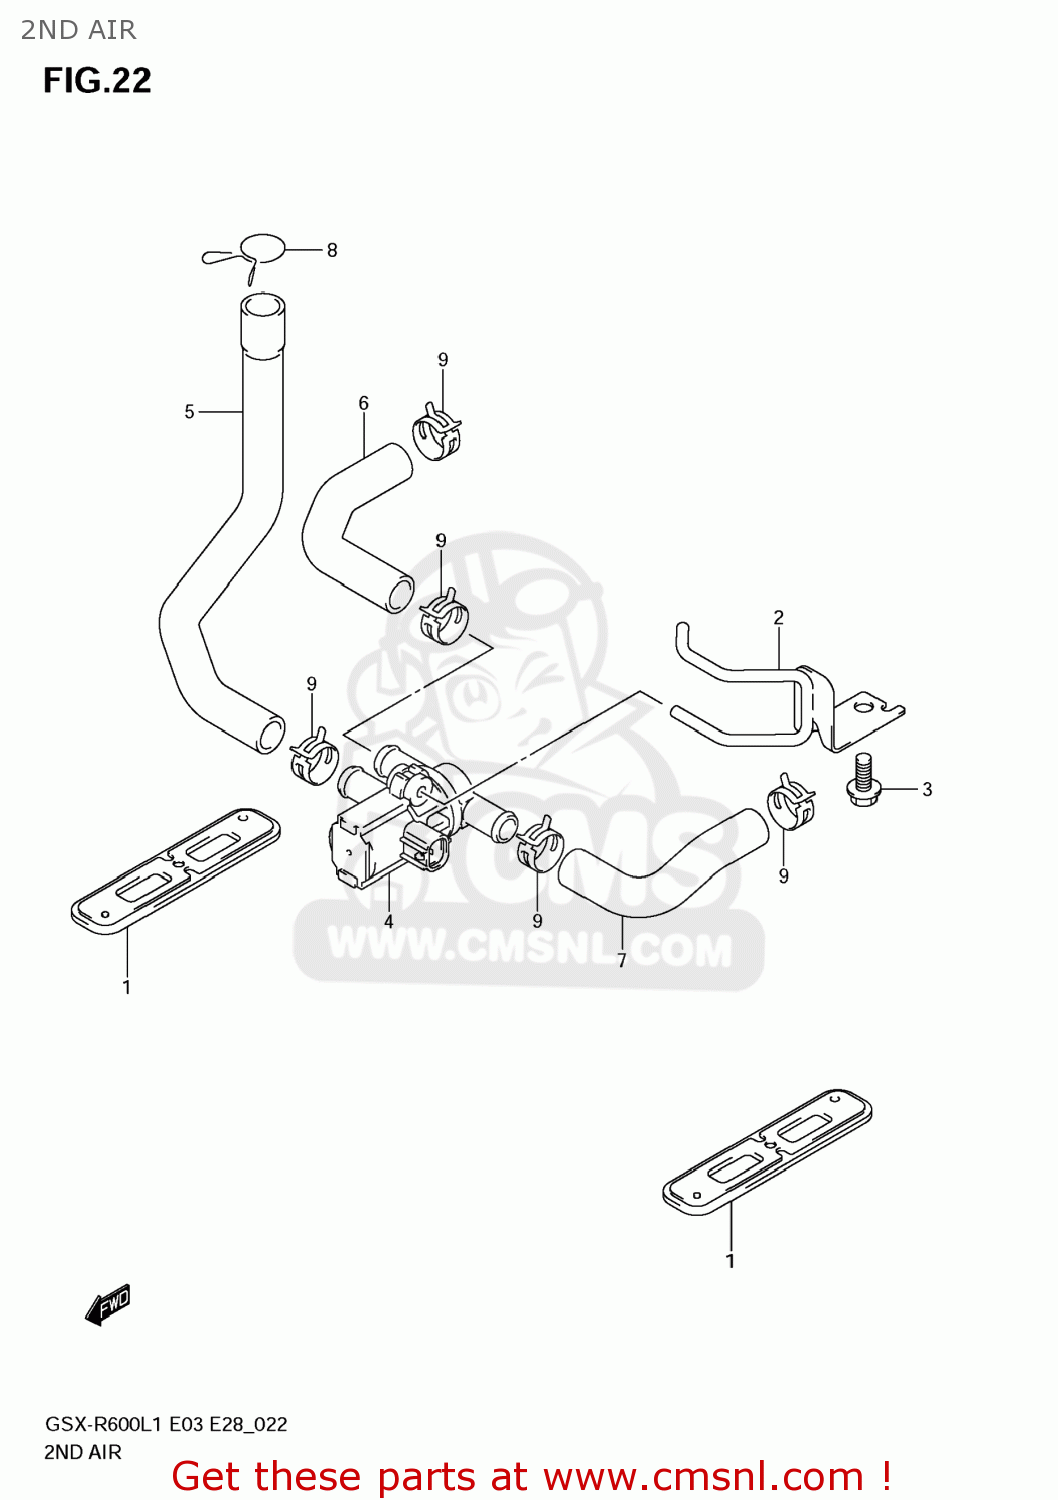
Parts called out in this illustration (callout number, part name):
1	VALVE ASSY,2ND AIR REED
2	BRACKET,2ND AIR VALVE
3	BOLT
4	VALVE ASSY,AIR CUT
5	HOSE,2ND AIR CLEANER
6	HOSE,2ND AIR VALVE,R
7	HOSE,2ND AIR VALVE,L
8	CLIP
9	CLIP
